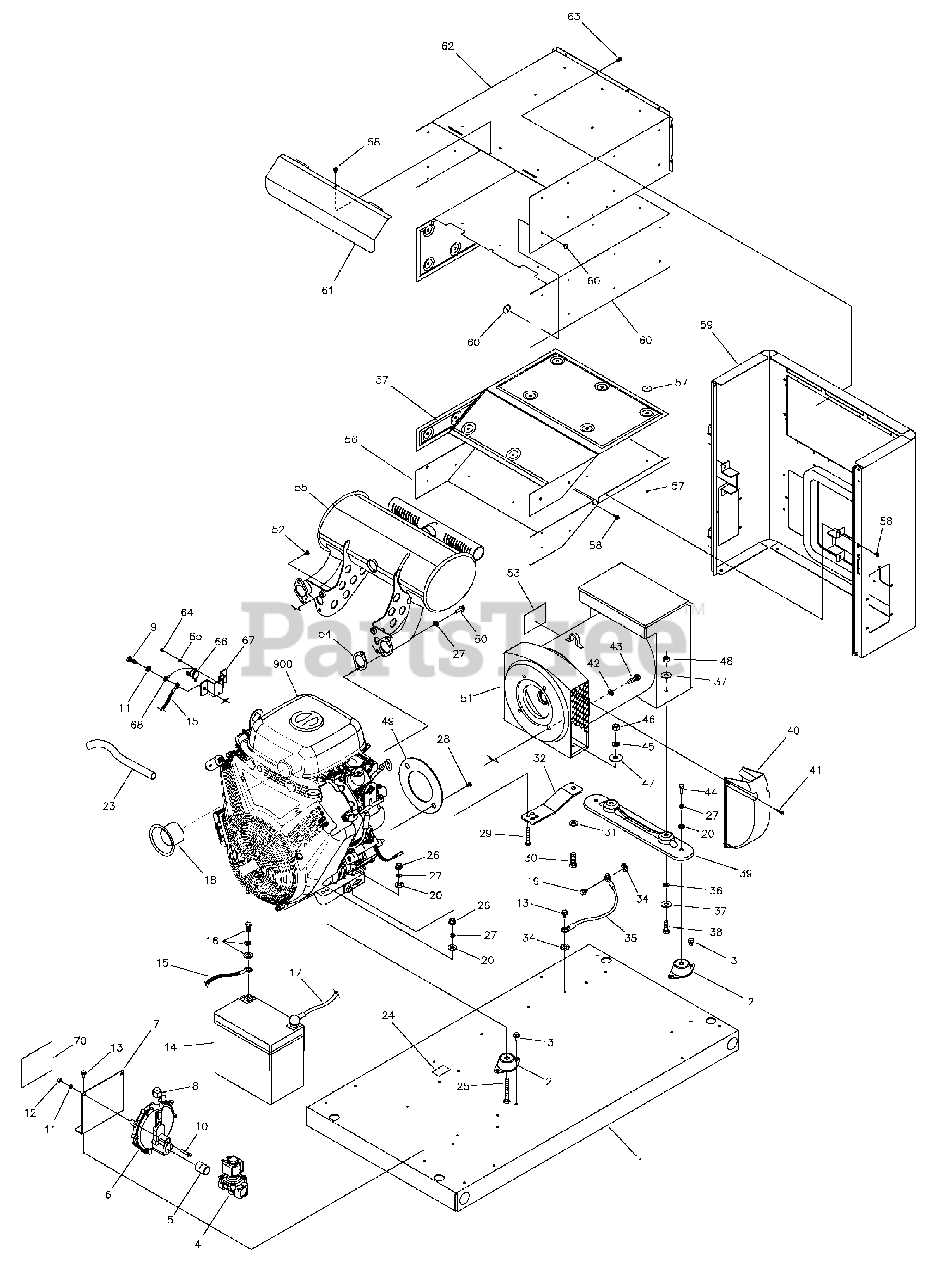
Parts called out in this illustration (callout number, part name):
1	BASE, Mounting
2	MOUNT, Vibration
4	SOLENOID, Gas Fuel
5	FITTING, Coupling
6	REGULATOR, NG/LPG
7	BRACKET, Mounting, Solenoid
9	*CAPSCREW, Hex Head, M6-1 x 16
10	*CAPSCREW, Hex Head, M6-1 x 30
11	*WASHER, Lock, 1/4
12	*NUT, M6-1
13	BOLT
16	KIT, Battery Hardware
19	*CAPSCREW, Hex Head, M6-1 x 12
20	*WASHER, Flat, 5/16-M8
23	HOSE, Oil Drain
24	DECAL, Oil Drain
25	*CAPSCREW, Hex Head, 5/16-18 x 2-1/2
26	*NUT, 5/16-18
27	*WASHER, Lock, 5/16-M8
28	*CAPSCREW, Hex Head, 5/16-24 x 3/4
29	*CAPSCREW, Hex Head, 5/16-18 x 2
30	*CAPSCREW, Hex Head, M12-1-3/4 x 35
31	*WASHER, M12
32	SUPPORT, Engine
34	*WASHER, Shakeproof, M6-1/4
36	*WASHER, Lock, 3/8
37	*WASHER, Flat, 3/8
38	*CAPSCREW, Hex Head, M10-1-1/2 x 30
39	SUPPORT, Alternator
41	*SCREW, Phillips Head, M5-0.8 x 20
42	*WASHER, Lock, 3/8
43	*CAPSCREW, 3/8-16 x 1-1/4
44	*CAPSCREW, Hex Head, 5/16-18 x 3/4
45	*WASHER, Lock, M12
46	*NUT, Hex, M12
47	*WASHER, Flat, M12
48	*NUT, M10-1.5
50	SCREW
51	ALTERNATOR (see page 7)
58	CRIMPTITE, 10-24 x 1/2
59	BULKHEAD, Alternator
61	COLLECTOR, Muffler Box
62	BOX, Muffler Top
63	SCREW, 10-32 x 5/8
64	*SCREW, Phillips Head, 4-40 x 0.19
65	*WASHER, Lock, #4
66	SWITCH, Temp
67	PLATE, Temp Switch
70	DECAL, Requirements, Fuel
900	**ENGINE
